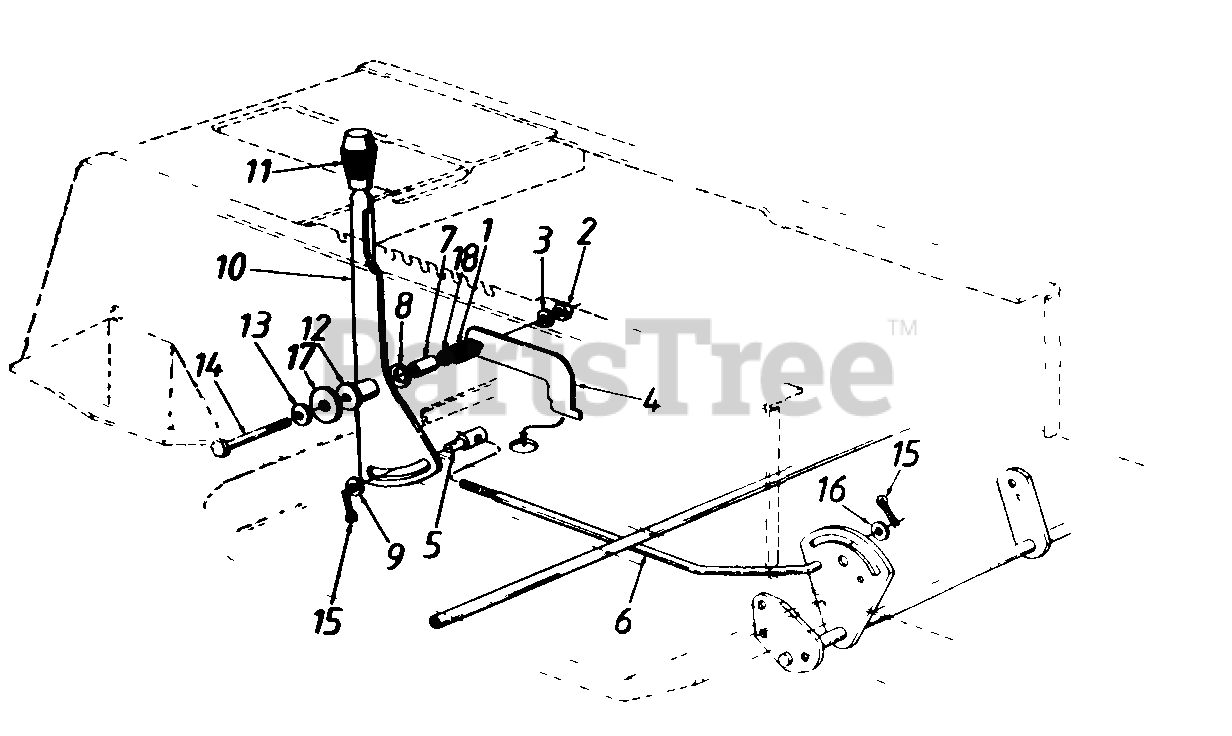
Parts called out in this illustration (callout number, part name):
1	Compression Spring
2	Hex Nut 5/16-18 Thd.
3	L-Wash 5/16" I.D.
4	Shift Lever Support
5	Ferrule 3/8-24 Thd
6	Speed Control Rod
7	Spacer 1.56" Lg
8	Bell-Wash .505" I.D. x 1"
9	Fl-Wash. .385" I.D. x .87"
10	Speed Selector Lever
11	Shift Knob
12	Spacer 1.46" Lg
13	Fl-Wash. .345" I.D. x .88"
14	Hex Bolt 5/16-18 x 3.25" Lg.
15	Cotter Pin 3/32" Dia. x 1"
16	Fl-Wash. .469" I.D. x .88"
17	Fl-Wash. .34" I.D. x 2.25"
18	Speed Nut 5/16-18 Thd.
